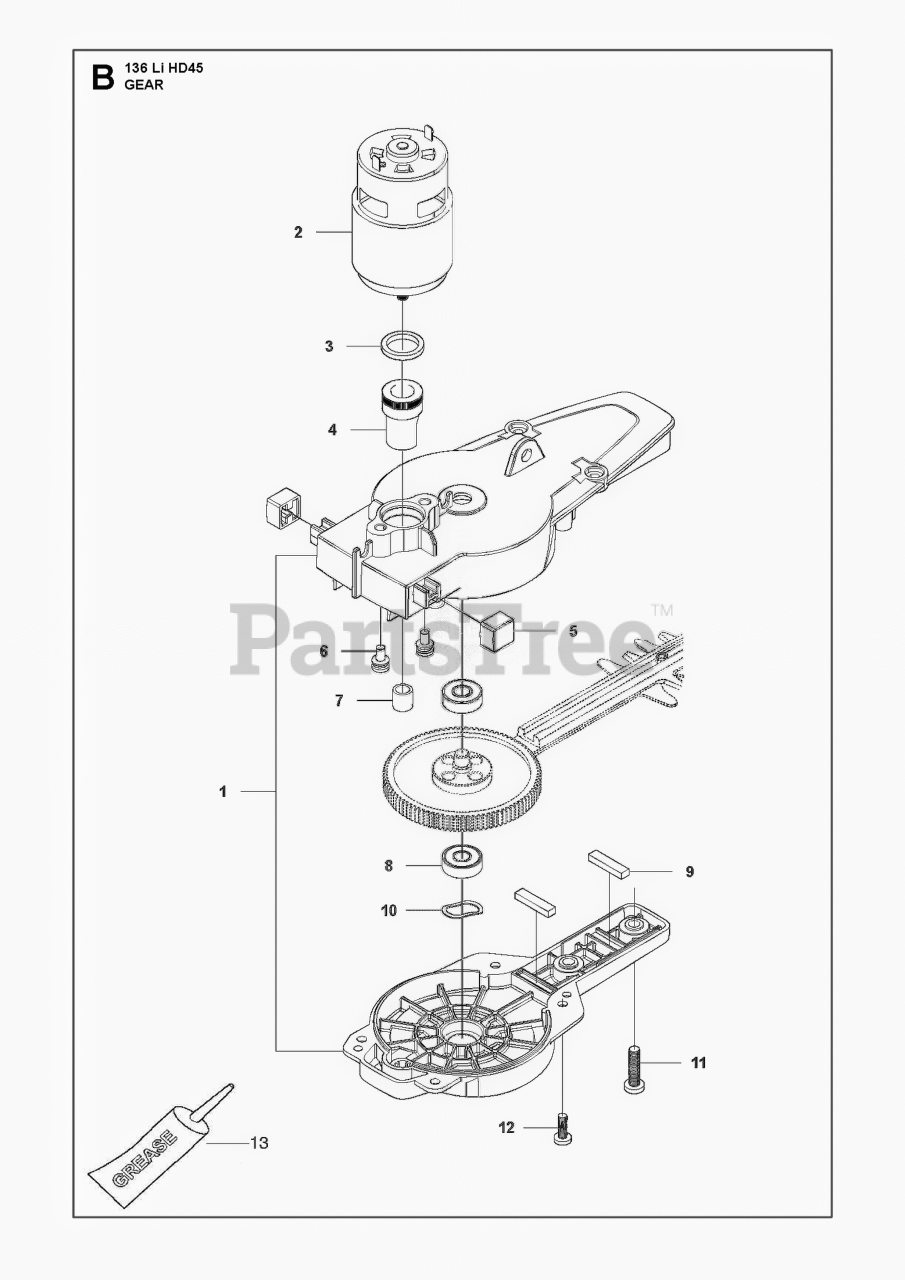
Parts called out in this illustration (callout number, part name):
1	GEAR BOX ASSEMBLY
5	SHOCK ABSORBING
7	NEEDLE BEARING
8	BALL BEARING
9	PAD DUSTPROOF
10	SPRING WASHER
11	SCREW M5X20
12	SCREW M4X12
13	GREASE
